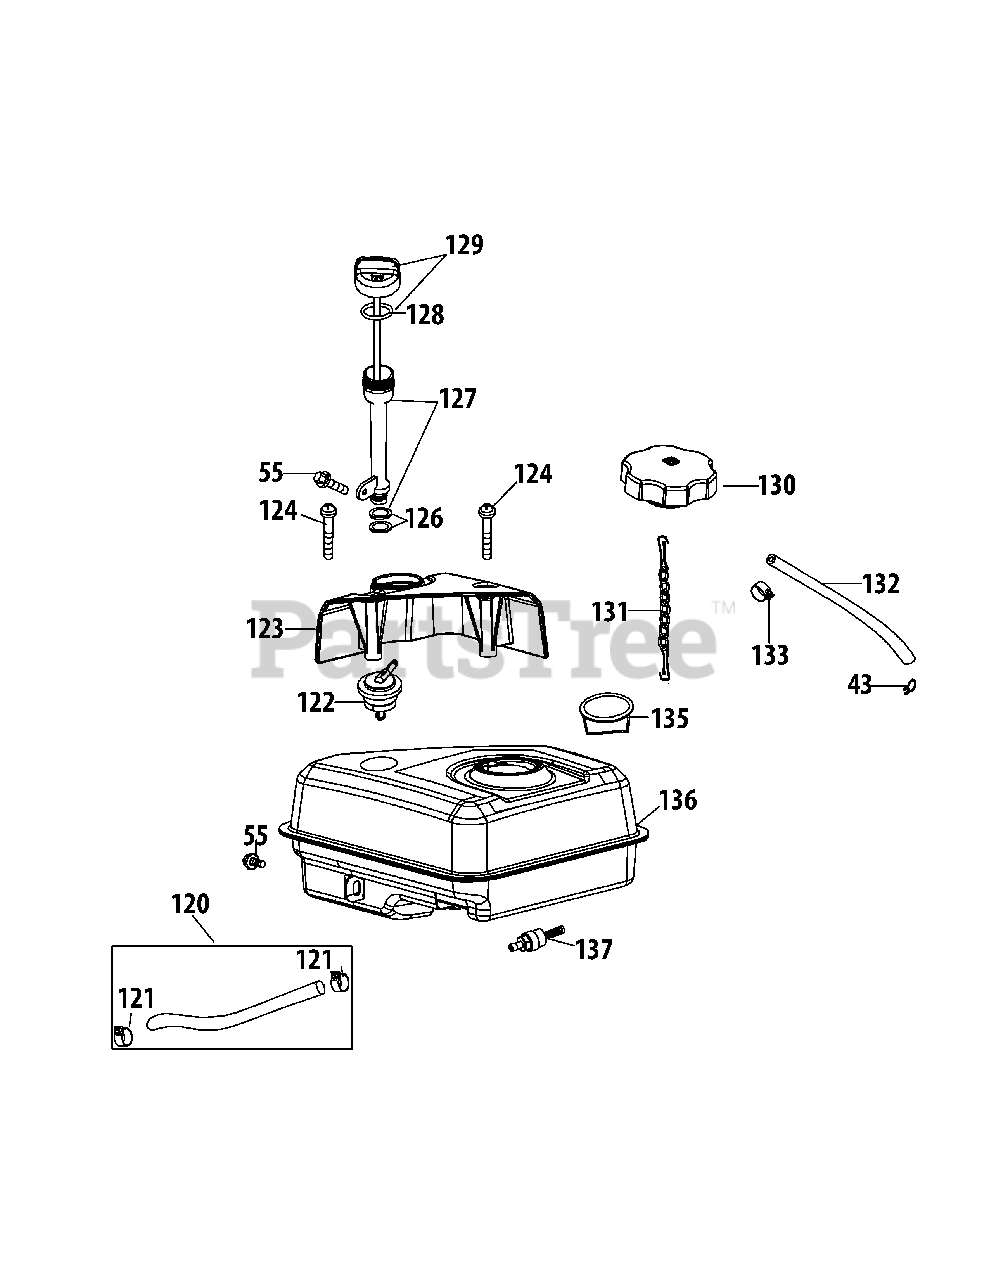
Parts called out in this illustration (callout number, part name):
43	Venting House Clamp
55	Bolt M6×12
120	Fuel line Kit
121	Fuel Hose Clamp
122	Roll Over Valve
123	Dipstick Decoration Cover
126	Oil Fill Tube O-Ring
127	Oil Fill Tube Asm
128	O-Ring 21×2.77
129	Dipstick Assy
131	Fuel Cap Chain
132	Evap House
133	Clamp, Fuel Hose
135	Fuel Level Indicator
136	Fuel Tank Body
137	Fuel Filter
